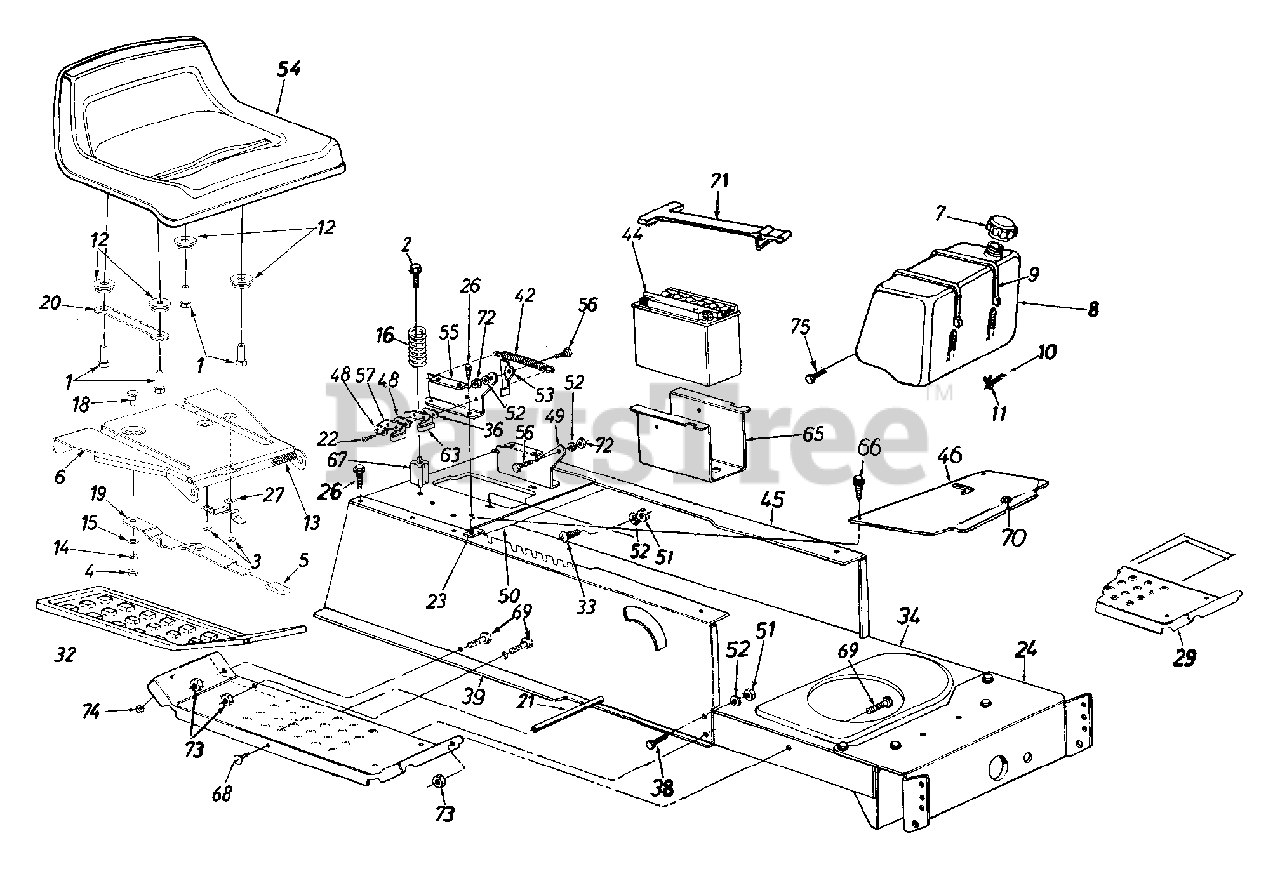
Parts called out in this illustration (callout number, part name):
1	Shoulder Screw 3/8-16 x .5
2	Hex Washer Tap Scr. 5/16-18 x 3.25"
3	Hx Scr. B-Tap Wash. #10-16: .38 Lg.
4	Lock Nut 1/4-20
9	Tie Strap
10	Fuel Line
13	Compression Spring
14	Wash. Spring .265 x .562 x .025
15	Fl. Wash. .344 ID x .62 OD x .03
16	Compression Spring
18	Shldr. Scr. .340 x .285 - 1/4-20
20	Seat Selector
21	Running Board Rod
22	Hex AB-Tap Scr. #8 x .50"
23	Speed Nut #10Z
26	Hex Washer AB-Tap Scr. 5/16 x .75"
33	Truss Mach. Scr. 5/16-18 x .75"
36	Insulator Boss Plate
38	Hex Bolt 5/16-18 x .75" Lg.
44	12-V Battery
52	L-Wash. 5/16" I.D.
53	Seat Lift Brkt.
54	Seat
56	Shld. Bolt .437" Dia. x .268"
57	Spring Switch
63	Safety Switch (Seat)
66	Truss Mach. B-Tap Scr. #10 x .5"
67	Spring Spacer
68	Pan Hd. Scr. 5/16-18 x .75"
69	Hex Bolt 5/16-18 x .75"
70	Snap Bushing
71	Battery Retainer Strap
72	Hex Nut 5/16-18 Thd.
73	Hex Sems Nut 5/16-18 Thd.
74	Hex Sems Nut 1/4-20 Thd.
75	Hex Screw 12-24 x .62
